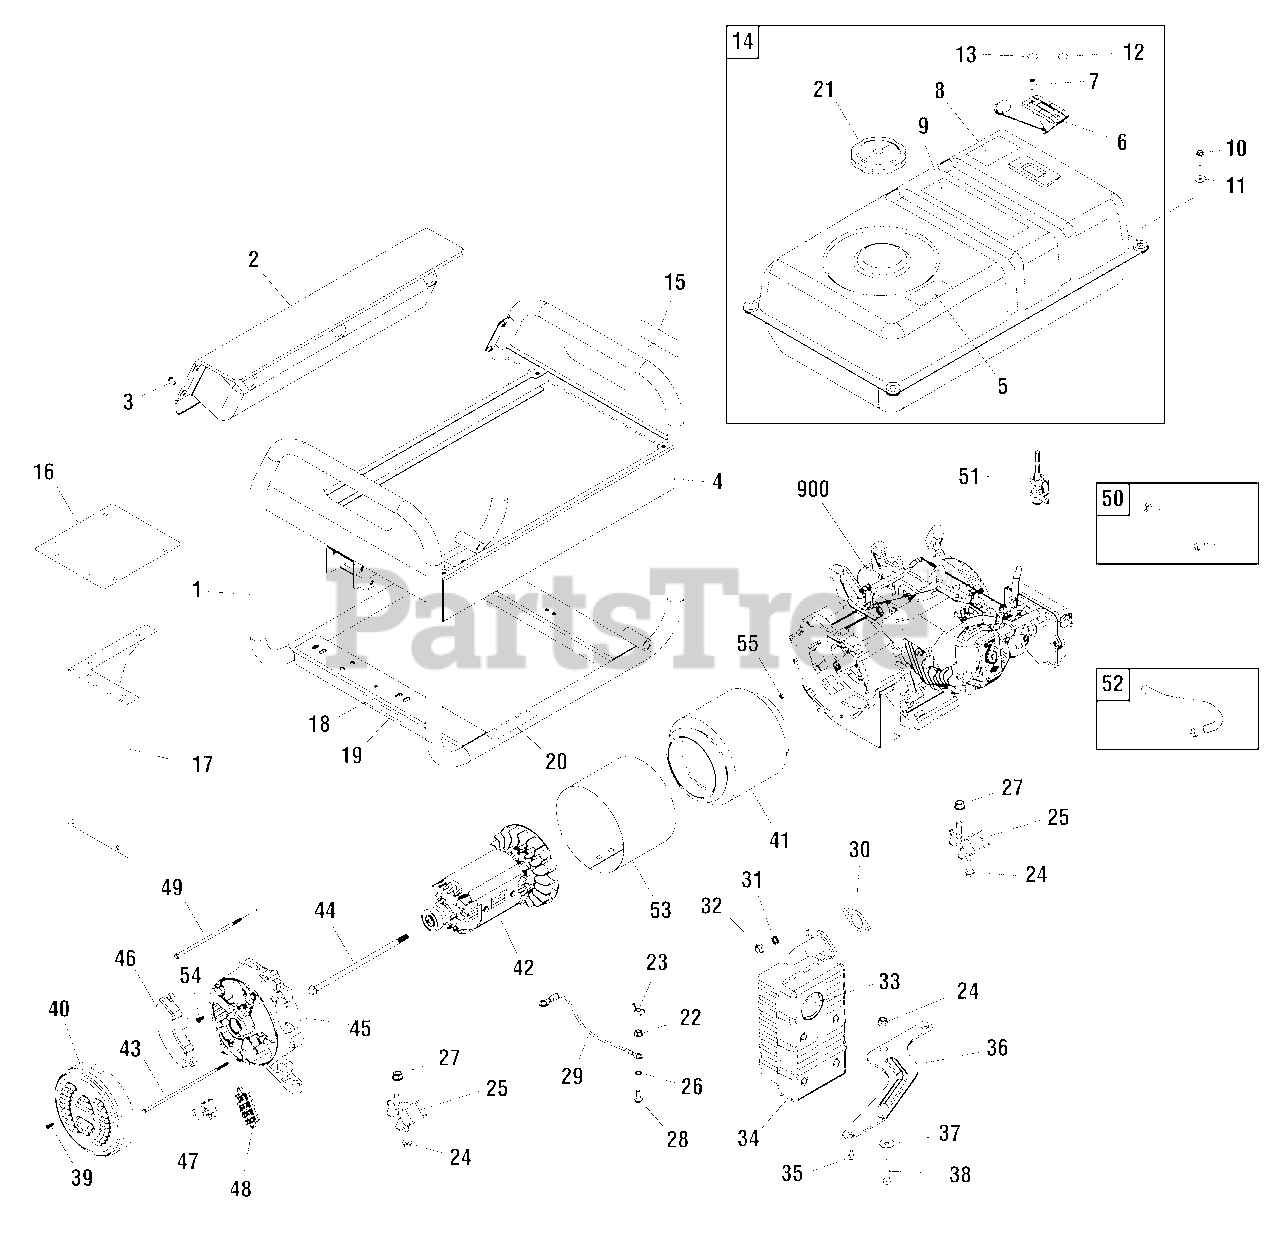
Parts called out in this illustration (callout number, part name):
22	* NUT, Flange Lock, M6
24	* NUT, Flange Lock, M8
25	MOUNT-VIBRATION
26	* WASHER, Shakeproof, Ext M6
27	* NUT, Flange Lock, M10
28	* SCREW, Flange, M6 x 16
30	GASKET
31	* WASHER, Lock, M8
32	* NUT, Hex, M8-1.25
35	* SCREW, Flange, M6 x 12
36	BRACKET, Muffler
37	* WASHER, Flat M8
38	CAPSCREW, Hex Head, M8-1.25 x 40
45	CARRIER-BEARING
46	VOLTAGE REGULATOR
50	KIT-FUEL HOSE
900	** ENGINE
